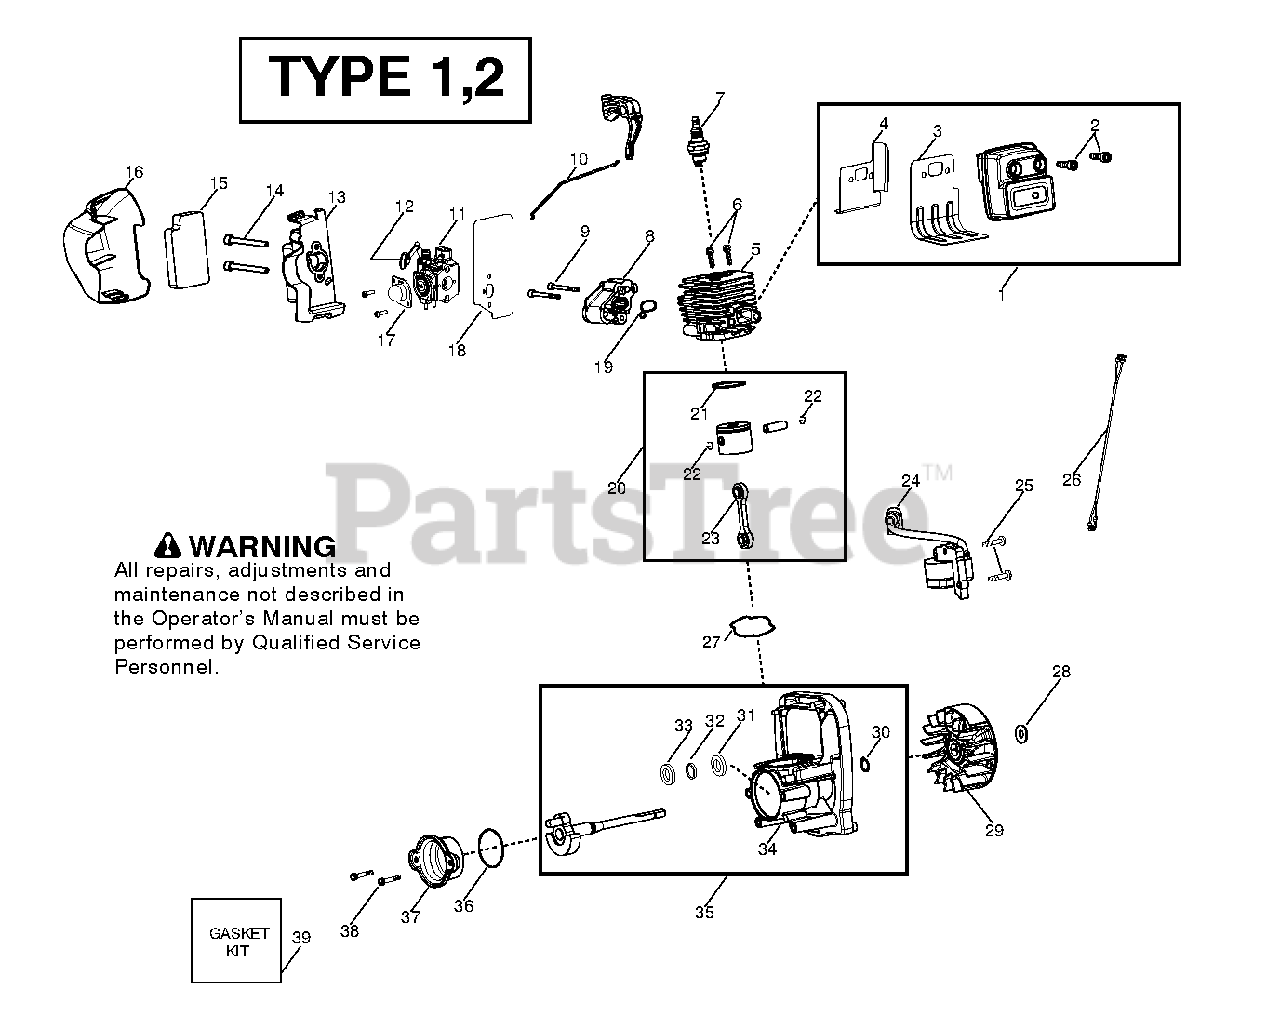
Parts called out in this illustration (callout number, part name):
1	Muffler Assembly
3	KIT GASKET 25CC
4	SHIELD MUFFLER HEAT
5	CYLINDER CHROME 25CC
7	PLUG-SPARK (RCJ-6Y)
8	ADAPTER CARBURETOR
10	LINKAGE THROTTLE
11	KIT CARBURETOR WT-875A
12	LEVER CHOKE WT-875
13	BASE AIRBOX RED
15	AIR FILTER FOAM
16	COVER AIRBOX BLACK
17	PURGE BULB 188-16
18	KIT GASKET 25CC
19	KIT GASKET 25CC
20	KIT PISTON CONN ROD
21	RING-PISTON
22	WRIST PIN RET.
23	KIT PISTON CONN ROD FORGED
24	KIT MODULE W/0 INTERRUPT
27	KIT GASKET 25CC
29	ASSY FLYWHEEL
30	RETAINING RING
31	OUTER BEARING
33	BEARING
34	ASSY CRANKCASE
35	ASSY CRANKCASE & CRANKSHAFT
36	KIT GASKET 25CC
37	ASSY REAR PLUG
39	KIT GASKET 25CC
